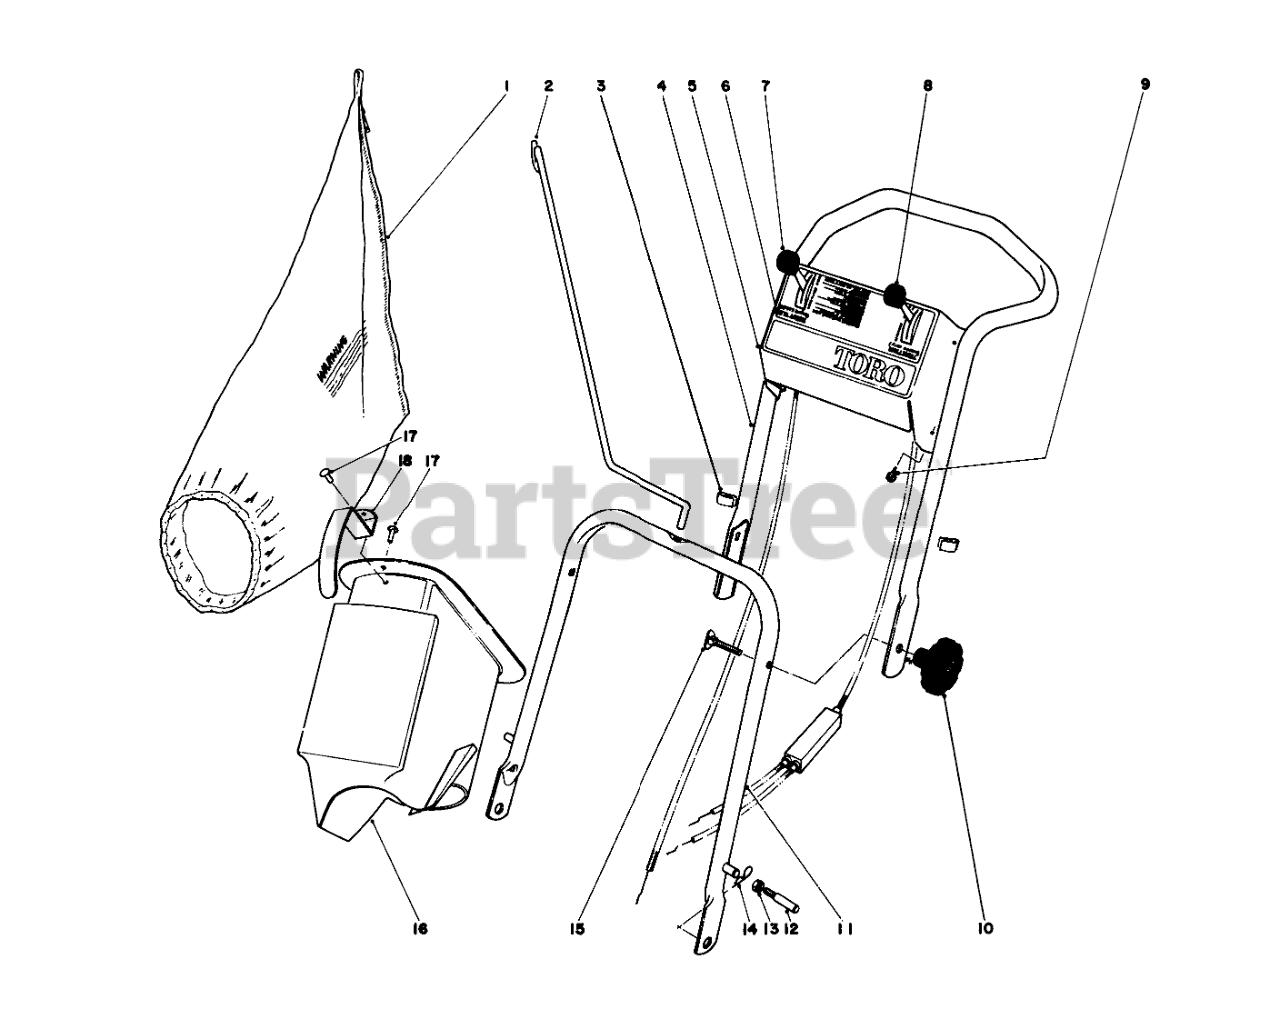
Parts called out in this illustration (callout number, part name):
1	BAG REPLACMNT44-0540
2	Bag Rod
4	UPPER HANDLE
5	Control Plate
6	Decal Control Plate
7	Control Throttle
8	Control Traction
9	SCREW-HWHTF
11	Lower Handle
12	HANDLE PIN
13	Nut
14	PIN-COTTER, HAIR
15	SCREW-HANDLE
16	Grass Chute (Incl. Ref.17 & 18)
17	RIVET 3/16 X 7/16
18	Handle Chute
